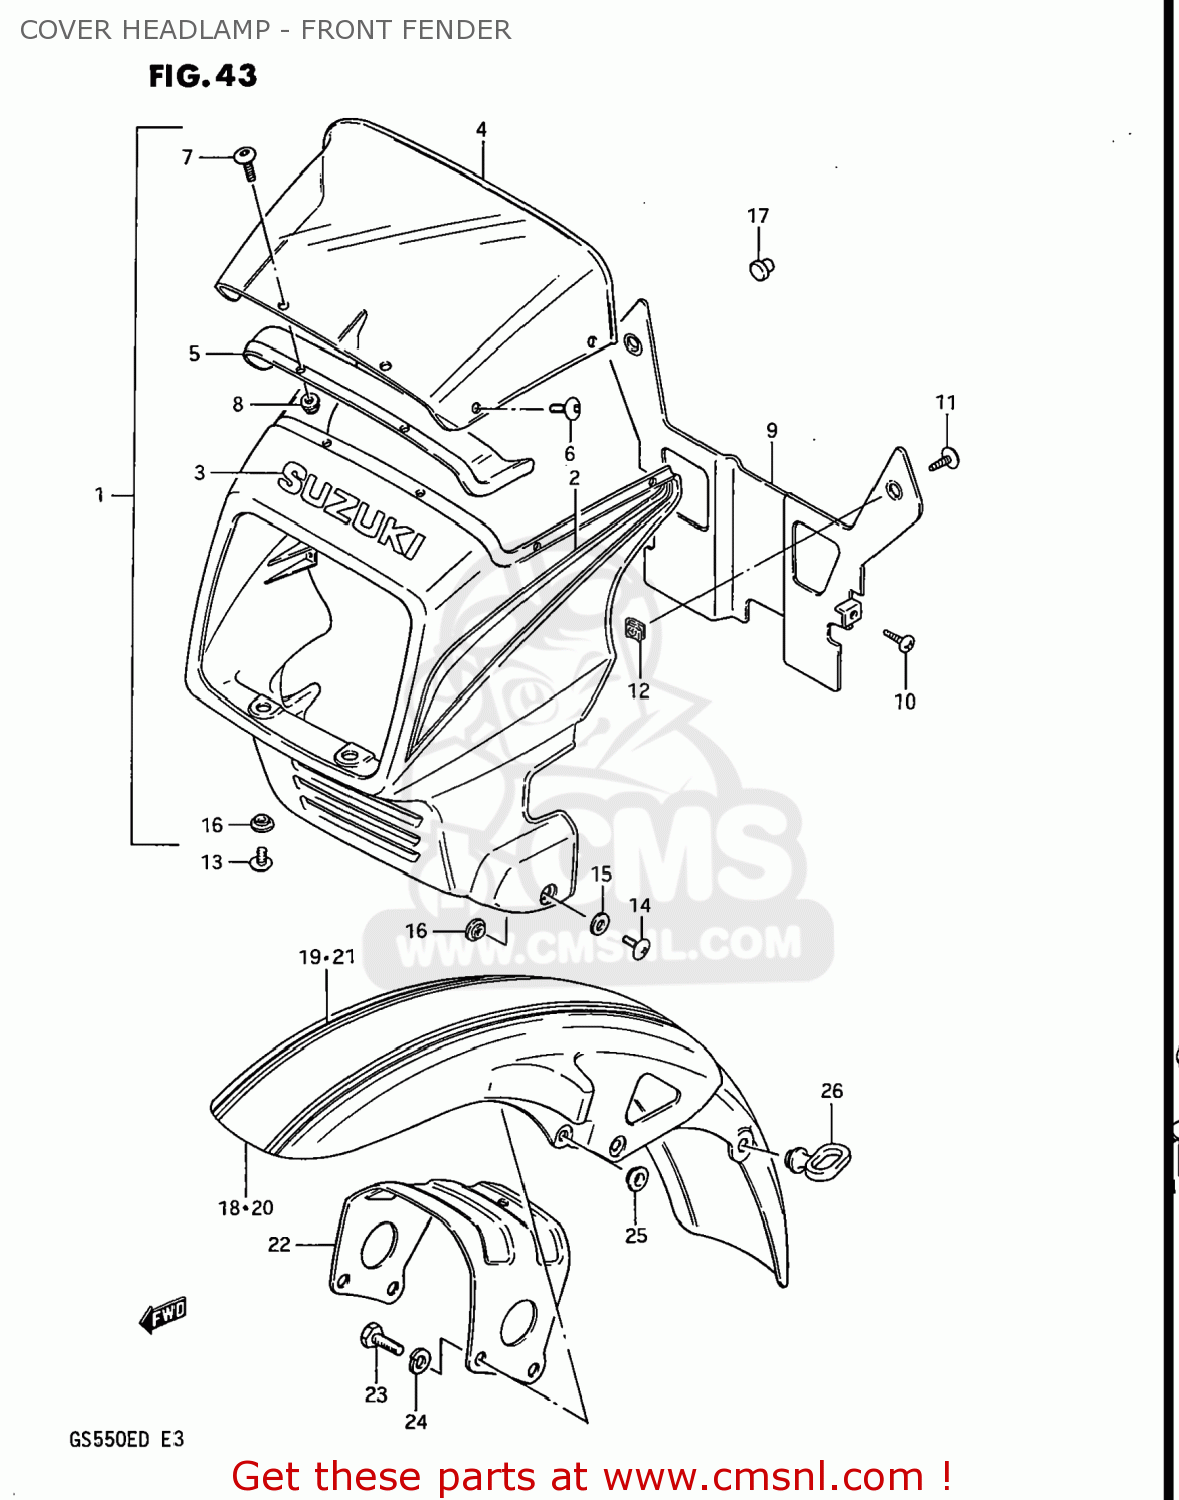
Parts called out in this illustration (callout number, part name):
1	HOUSING,HEADLAMP (COWLING)
2	TAPE SET,HEADLAMP
3	EMBLEM,HEADLAMP
4	WINDOW,COVER HEADLAMP
5	COVER,HEADLAMP,UPPER
6	SCREW(5X12)
7	SCREW
8	NUT
9	PLATE,HEADLAMP COVER
10	SCREW
11	SCREW
12	NUT
13	SCREW 6X12
14	SCREW 6X12
15	WASHER (6.5X18X1.6)
16	WASHER
17	PLUG
18	FENDER,FRONT
19	TAPE SET,FRONT FENDER
20	FENDER,FRONT
21	TAPE,FRONT FENDER
22	BRACE,FRONT FENDER
23	BOLT
24	LOCK WASHER
25	WASHER
26	GUIDE,CABLE
